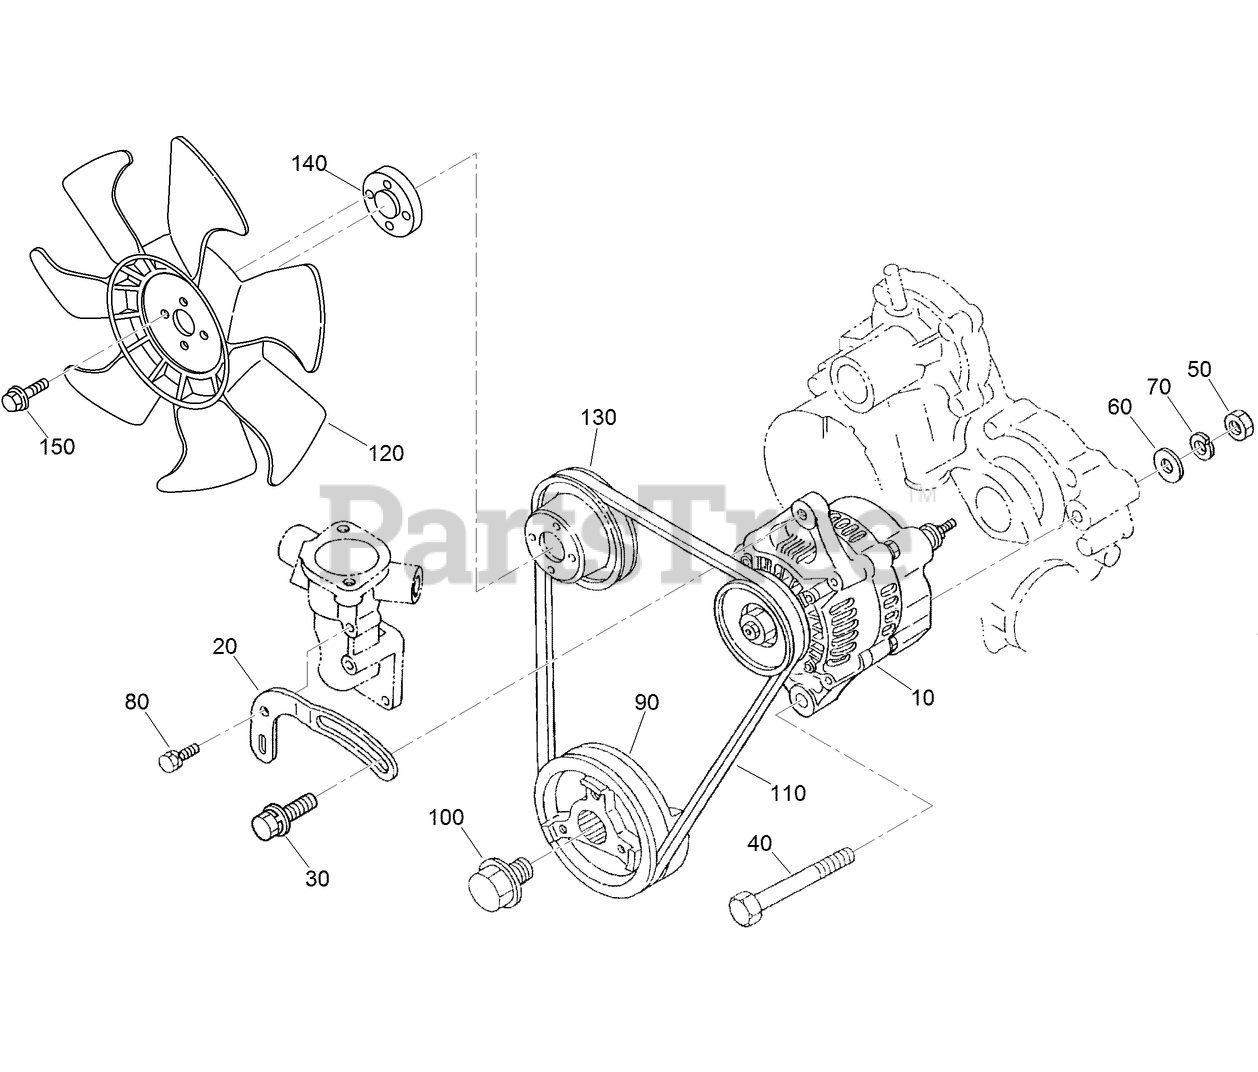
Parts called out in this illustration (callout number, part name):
10	ALTERNATOR ASM
20	STAY-DYNAMO
60	WASHER-PLAIN
70	WASHER-SPRING
90	PULLEY-DRIVE, FAN
110	V-BELT
120	FAN-ENGINE
130	PULLEY-FAN
150	BOLT-FLANGE
